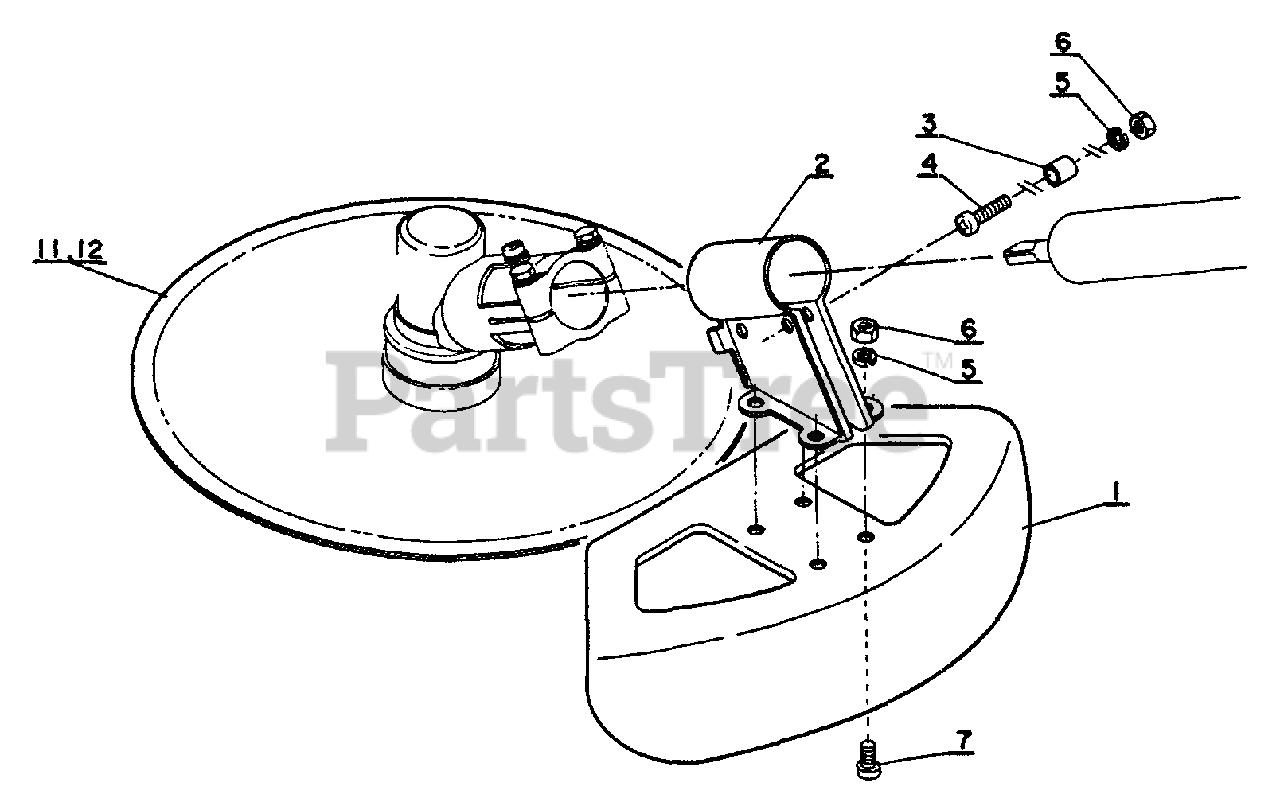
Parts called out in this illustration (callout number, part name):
2	SAFETY GUARD SET PLATE
3	SPACER, GUARD
4	SCREW 5×18
5	WASHER, SPRING 5
6	NUT M5
7	SCREW 5×8
11	BLADE - 10"
12	BLADE - 8 TOOTH
